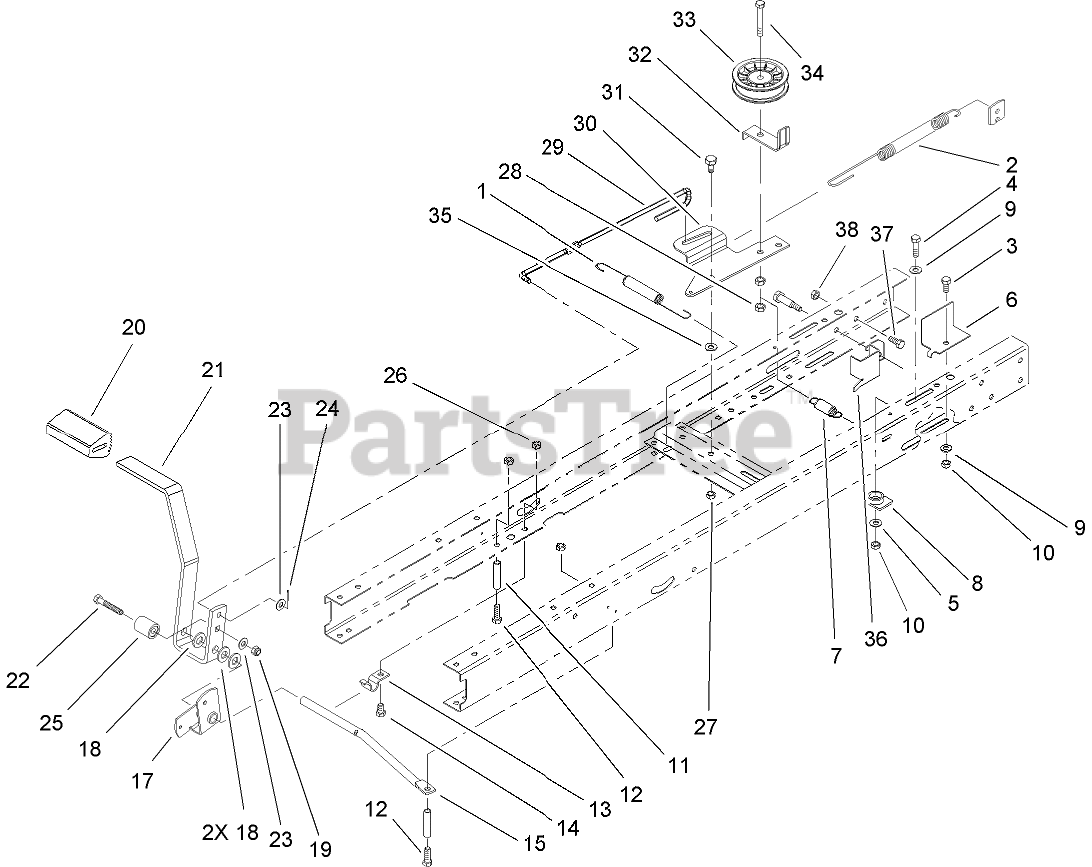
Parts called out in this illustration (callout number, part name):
1	SPRING-EXTENSION
2	SPRING-BRAKE
3	SCREW-HH
4	SCREW-HH
5	WASHER-PIVOT
6	BRACKET-BELT, GUIDE
7	SPRING-EXTENSION
8	GUIDE-CABLE
9	WASHER-PLAIN
10	NUT-LOCK, NI
11	TUBING-SPACER
12	SCREW-HH
13	CLAMP-PIVOT, SHIFT
14	SCREW-HH
15	ROD-PIVOT, PEDAL
17	BELLCRANK
18	WASHER-FLAT
19	NUT-LOCK, NI
20	PAD-PEDAL
21	PEDAL-CLUTCH/BRAKE, HYDRO
22	SCREW-HH
23	WASHER-PLAIN
24	PIN-COTTER
25	SPACER
26	NUT-LOCK, NI
27	NUT-LOCK, NI
28	NUT-LOCK, NI
29	ROD-CLUTCH/BRAKE
30	ARM-IDLER
31	BOLT-SHOULDER
32	GUIDE-IDLER, BELT
33	PULLEY-IDLER
34	SCREW-HH
35	WASHER-PIVOT
36	BRACKET-BELT, GUIDE
37	SCREW-HH
38	NUT-LOCK, NI
